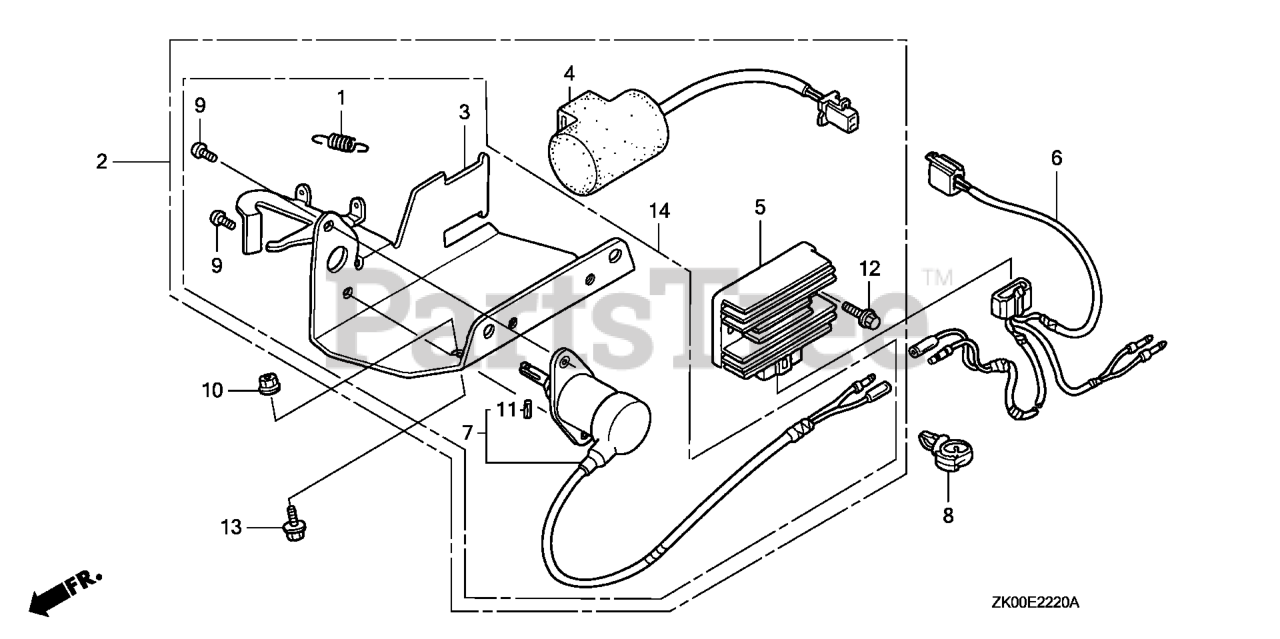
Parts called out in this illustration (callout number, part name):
1	SPRING, CHOKE RETURN
2	THROTTLE ASSY., AUTO
3	LEVER, SOLENOID THROTTLE
4	CONDENSER UNIT
5	RECTIFIER ASSY., REGULATOR
6	SUB-HARNESS ASSY.
7	SOLENOID ASSY., AUTO THROTTLE
8	CLIP, WIRE HARNESS (25MM)
9	SCREW, PAN (5X8)
10	NUT, FLANGE (6MM)
11	PIN, SPRING (2.5X16)
12	BOLT, FLANGE (6X16) Use from Engine SN 2056820.
13	BOLT, FLANGE (6X25)
